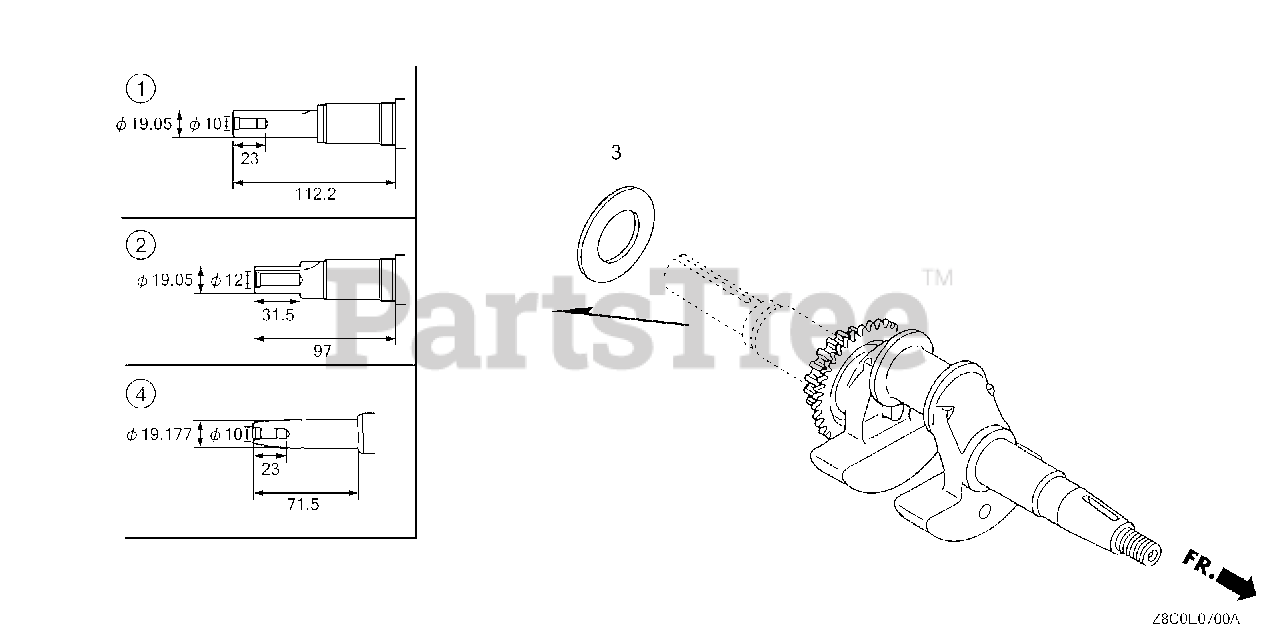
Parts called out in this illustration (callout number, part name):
1	CRANKSHAFT KIT
1	CRANKSHAFT
3	WASHER, THRUST
